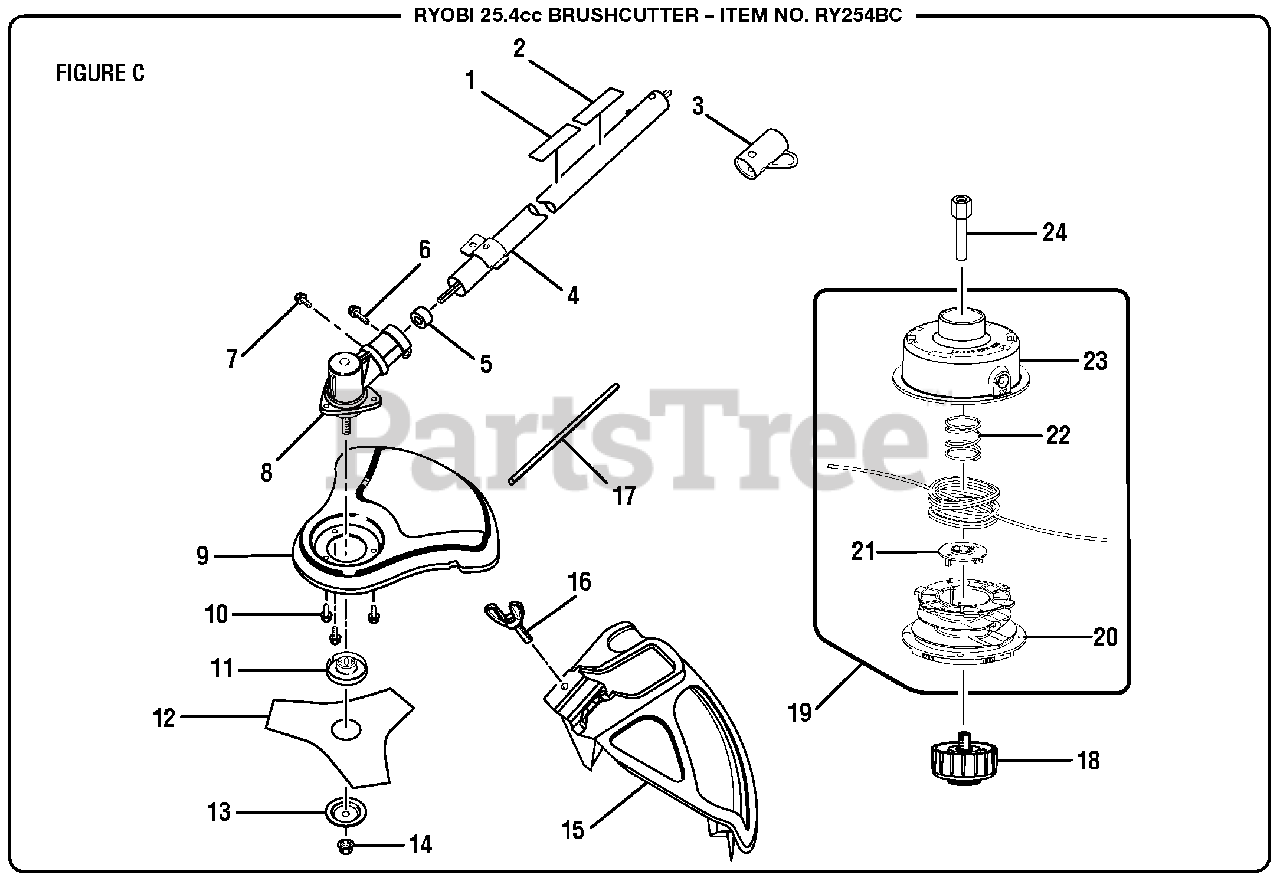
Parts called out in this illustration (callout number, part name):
1	Expand-it Label
2	Brushcutter Safety Label
3	Storage Hanger Cap
4	Lower Straight Shaft Boom Assembly
6	Screw (1/4-20 x 1-1/4 in, Hex Washer Hd ST)
7	Screw (10-24 x 5/8 in, Hex Washer Hd ST)
8	Gear Case Assembly
9	Brushcutter Guard
10	Screw w/Washer (10-24 x 1/2 in, Slotted Hex Hd)
11	Flanged Washer
13	Cupped Washer
14	Lock Nut (M8 x 125 in, Left Hand Threads)
15	Grass Deflector Assembly
16	Screw (1/4-20 x 7/8 in)
17	Gear Head Locking Tool
18	Bump Knob (Red)
19	Trimmer Head Assembly (095)
20	Spool Assembly
21	String Guide
22	Compression Spring
23	Housing and Eyelet Assembly
24	Trimmer Head Shaft Adaptor
